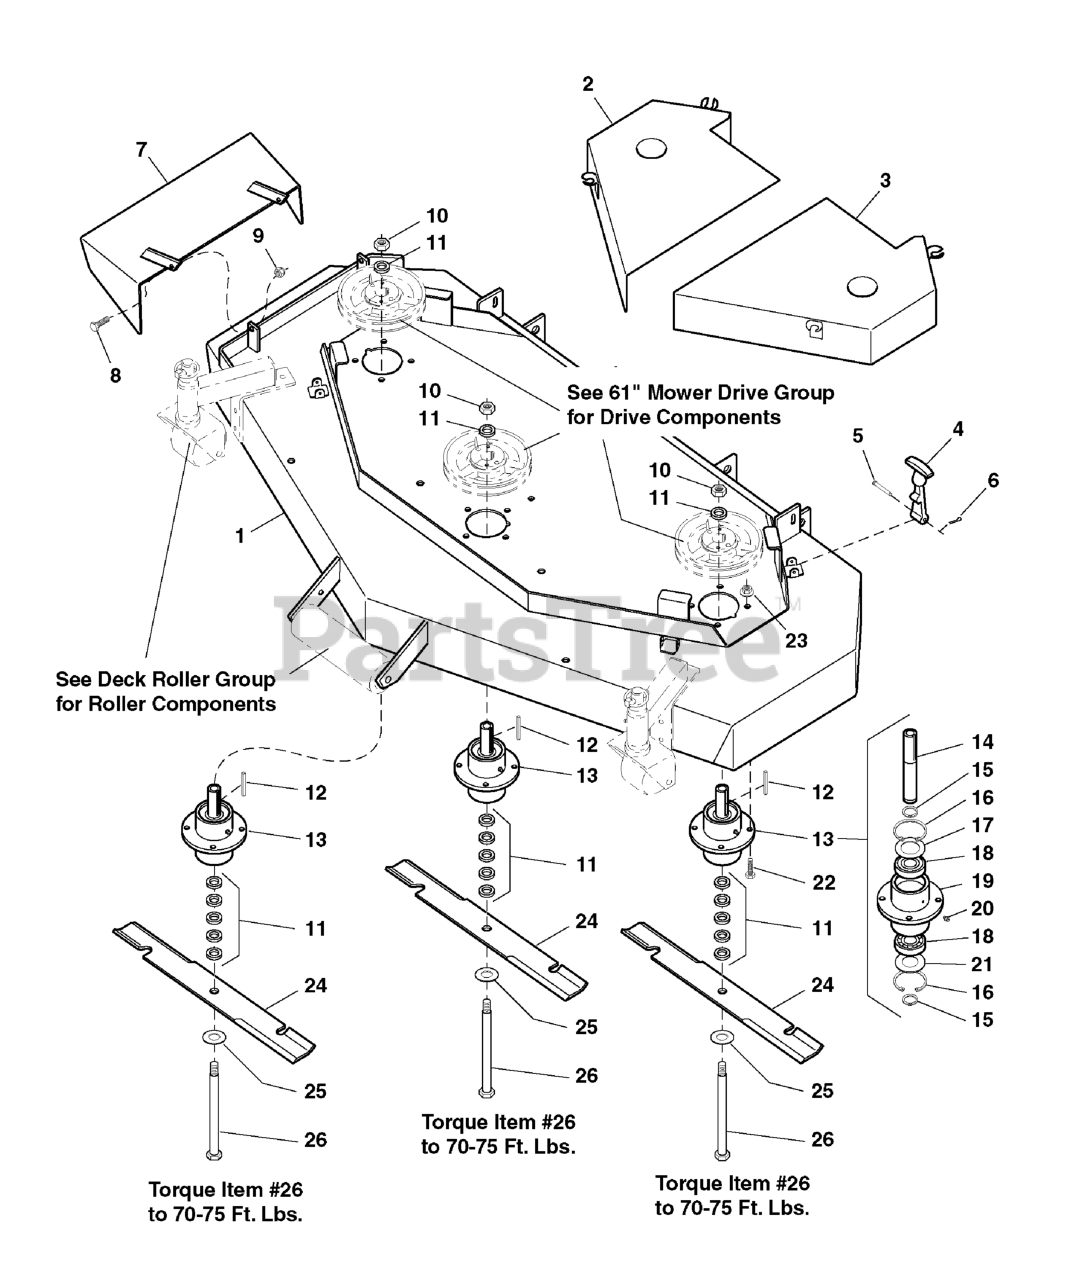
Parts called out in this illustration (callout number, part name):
1	DECK SHELL W/DECALS, 61, Z61
2	SPINDLE COVER-RH
3	SPINDLE COVER-LH
4	RUBBER LATCH
5	CLEVIS PIN
6	COTTER PIN
7	CHUTE, DISCHARGE WELDMENT
8	BOLT, 5/16-18 X 1 GD5 YZ
9	NUT, 5/16-18 Hex Nylon Lock
10	NUT, 5/8-11 Hex
11	SPACER, .63 x 1.06 x .23
12	KEY, 1/4 SQ. X 2-1/2
13	SPINDLE ASSEMBLY, Complete
14	SPINDLE SHAFT
15	SNAP RING, External
16	SNAP RING, Internal
17	SPINDLE WASHER, Top
18	BEARING
19	SPINDLE HOUSING
20	GREASE FITTING
21	SPINDLE WASHER, Bottom
22	BOLT, 5/16-18 x 1-1/4
23	NUT, 5/16-18 HEX SERRATED FLANGE (LARGE)
24	MOWER BLADE, 21"
25	WASHER, 5/8" USS
26	BOLT, 5/8-11 x 9-1/2
